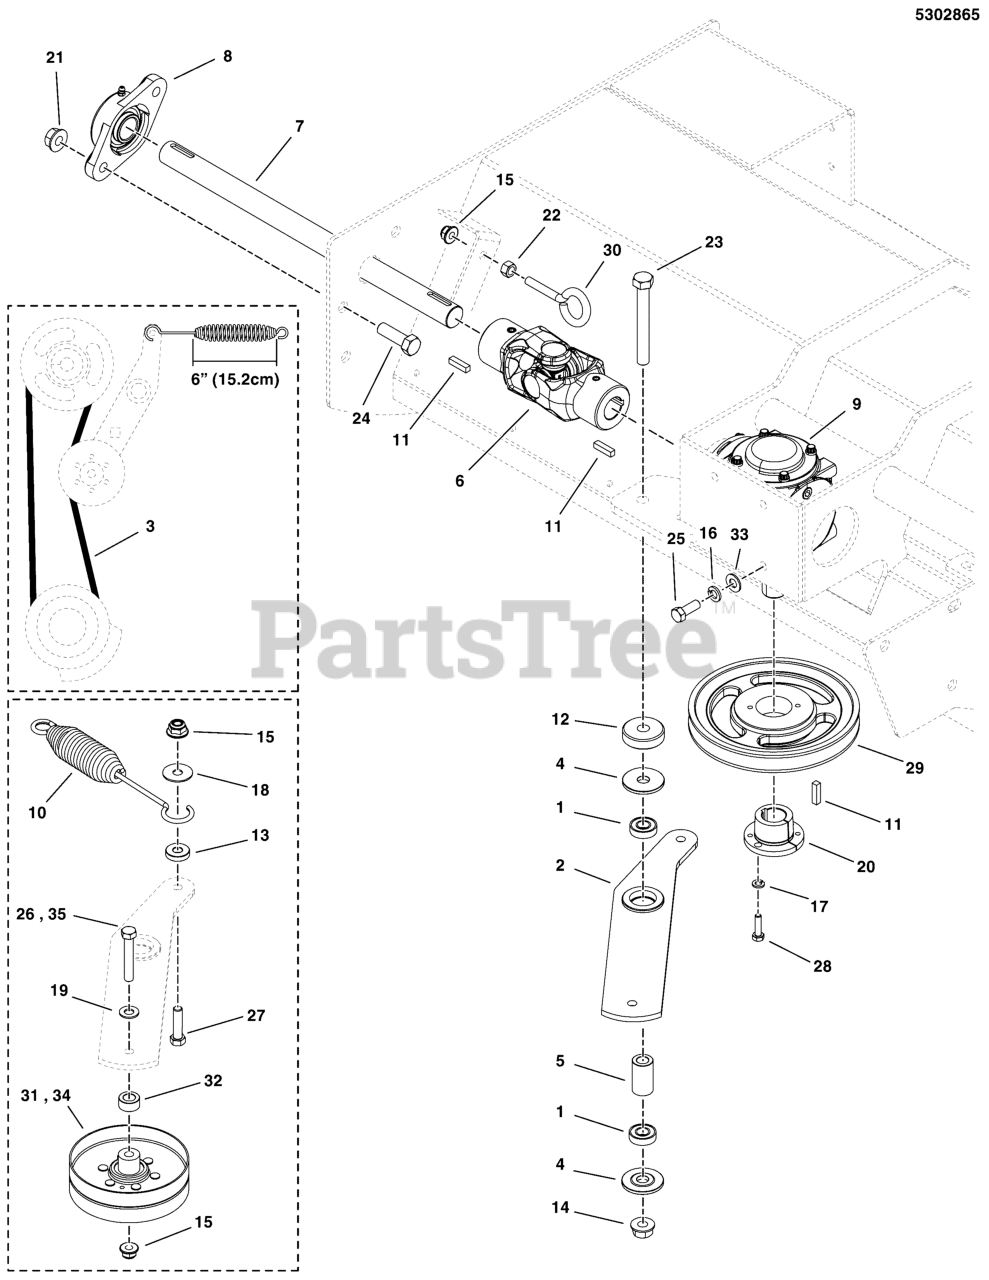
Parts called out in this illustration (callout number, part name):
1	BEARING, BALL, AXLE
2	WELD, IDLER ARM, FLAIL - RED
3	BELT, B-SEC, 63.3" EL, LGE ARAMID WRPD
4	SPACER, IDLER ARM, 1/2"
5	SPACER, .52 X .84 X 1.53, PM
6	UNIVERSAL JOINT ASM, 1"
7	SHAFT, 1" DIA X 18.19
8	BEARING, 2 BOLT FLANGE, 1", CAST
9	GEAR BOX, RIGHT ANGLE
10	SPRING, EXTENSION, SWIVEL. LONG HOOK
11	KEY, 1/4" SQR. X 1-1/4, RD ENDS
12	SPACER, .59 X 1.50 X .25
13	SPACER, .39 X 1.00 X .25
14	NUT, Hex Flange, Nylock, 1/2-13
15	NUT, 3/8-16 HEX NYLOCK FLANGE
16	WASHER, 5/16 LOCK CZ
17	WASHER, 1/4 LOCK
18	WASHER-3/8 FENDER
19	WASHER, 3/8 SAE
20	BUSHING, TAPERED HUB
21	NUT, 1/2-13 HEX NYLON LOCK
22	NUT, 3/8-16 HEX
23	BOLT, 1/2-13 X 4" GD5 CZ
24	BOLT, 1/2-13 X 1-1/2 GD5 CZ
25	BOLT, 5/16-18 X 1 GD5 YZ
26	BOLT, 3/8-16 X 2-1/2" GD5 CZ
27	BOLT, 3/8-16 X 1-1/2" GD5 CZ
28	BOLT, 1/4-20 X 1" GD5 CZ
29	PULLEY, SPINDLE, BH72
30	EYE BOLT, 3/8-16 X 6, 3.0 THREAD
31	PULLEY-IDLER, 5.00OD, .385ID, 1.50W STL
32	SPACER, .39 X 1.00 X .25
33	WASHER, 5/16 F436 FLAT
34	PULLEY, IDLER, DOUBLE FLANGED, 4IN
35	BOLT, 3/8-16 X 2, GD5, CZ
